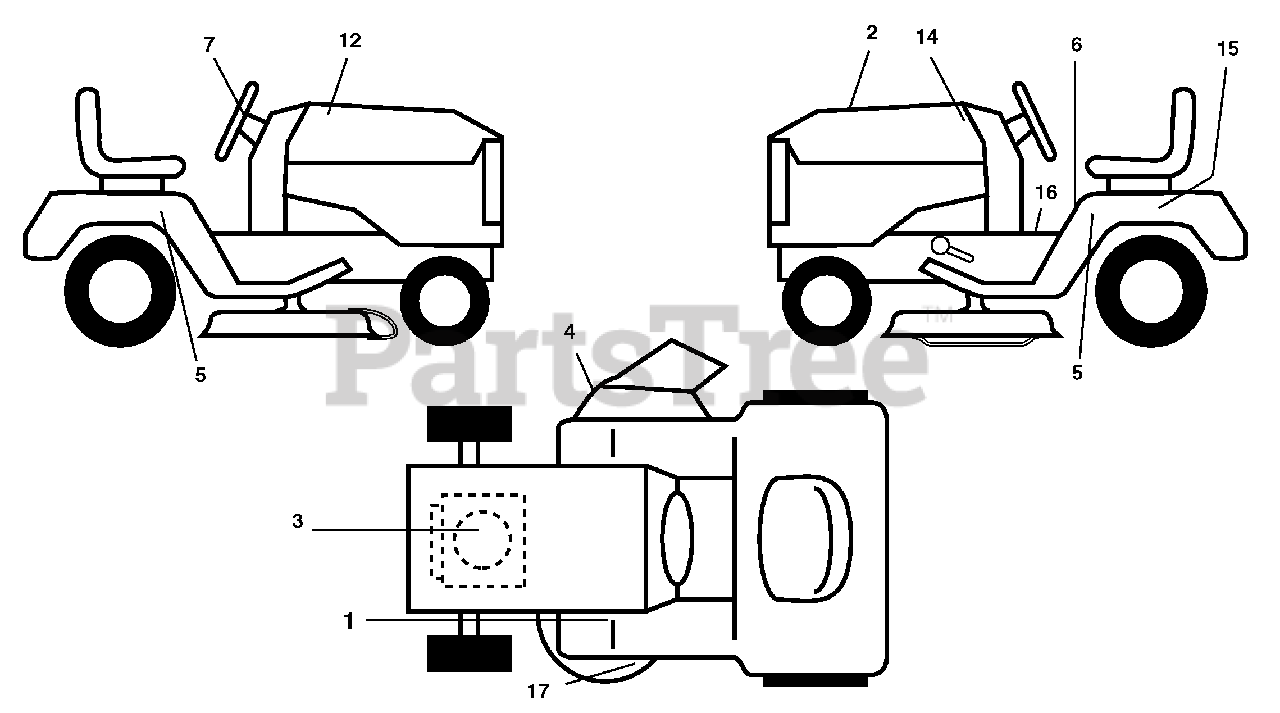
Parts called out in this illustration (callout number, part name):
1	Decal, Clutch/Brake Eng/Fr
2	Decal, Replacement
3	Decal, Engine HP
4	Decal Warning
5	Decal SDFNDR 5SP
6	Decal, Fender Danger English
7	Decal Ins Str Wh
12	Decal, Hood RH
14	Decal, Hood LH
15	Decal, Caution, Battery
16	Decal, Oper Sdl P/L Gear Dr Eng
17	Decal, V-Belt Sch.
17	Decal, Handle Lft Height Adj.
17	Manual, Operator's (E&F)
17	Manual, Parts (E&F)
